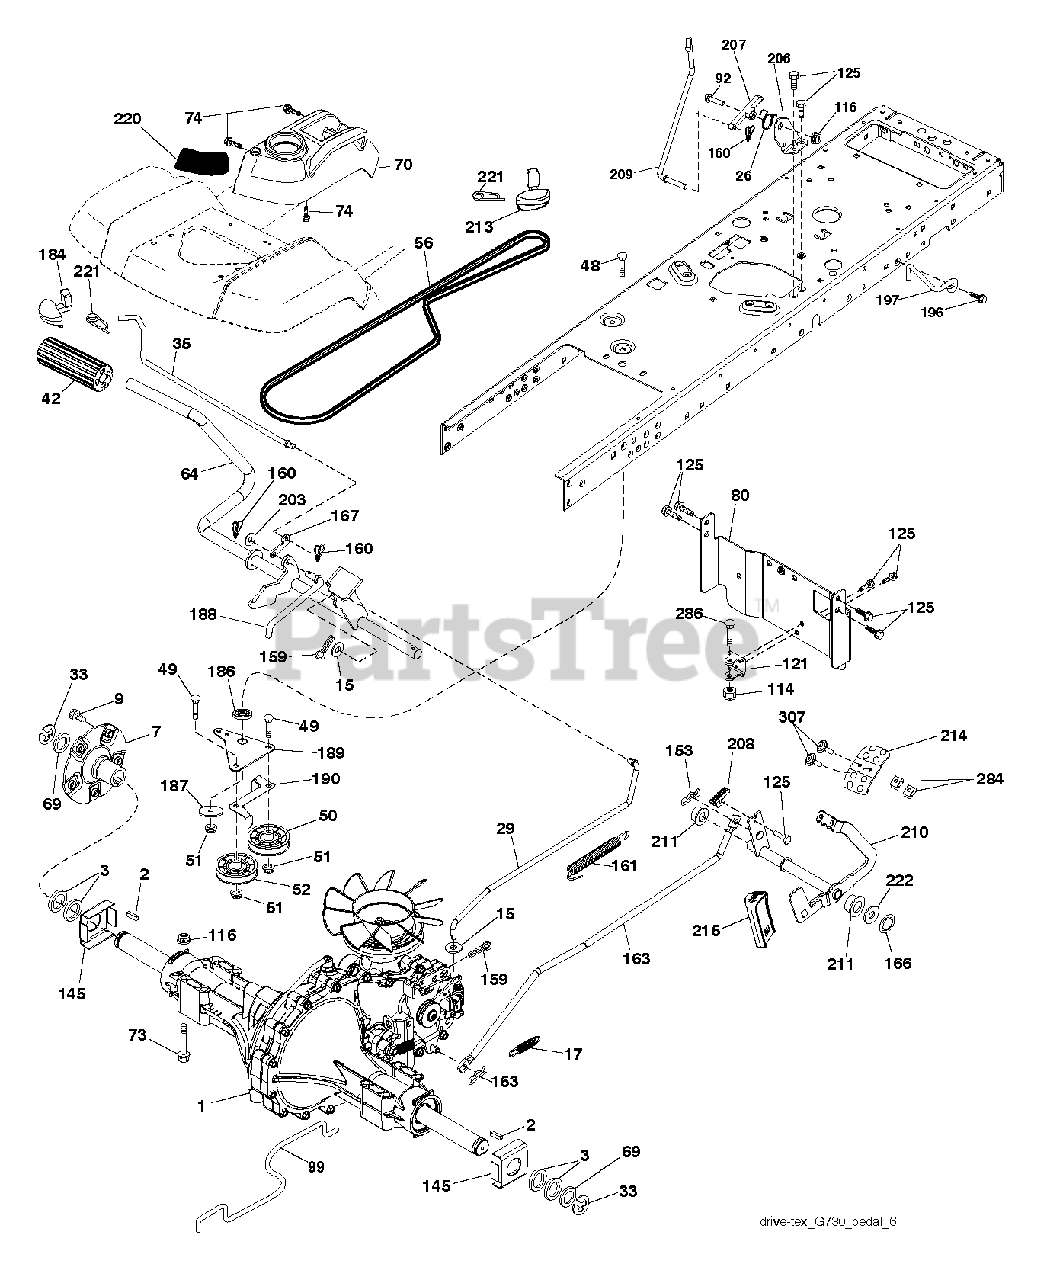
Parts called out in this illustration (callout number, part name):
2	KEY 1/4 X 2.5
7	HUB.ASM.WHEEL.REAR.23"TEX
15	WASHER
17	SPRING.BRAKE.HG3000/3500
26	SPRING.RETURN.CRUISE
33	E RING HYT
35	ROD.BRAKE.PARTK.HUSQ.TEX
42	PEDAL COVER T
48	BOLT.3/8-16X1.50
50	IDLER.FLAT.910.OFFSET
51	NUT LOCK FLG 3/8-16 UNC
52	IDLER.V-GROOVE.910.OFFSET
56	V-BELT.GROUND.DRIVE.
64	SHAFT.ASM.PEDAL.BRK.CNTR
70	CONSOLE.ASM.RH.GT.FC.HUSQ
73	BOLT HEX FLGHD 5/16-18X3 GR. 5
74	SCREW.HI-LO.CONSOLE
80	STRAP.TORQUE.YT.G700
92	BOLT
99	SPRING.BYPASS.YT.G700
114	NUT.71038.31-18.HEX.NYLOCK
116	NUT LOCK HEX FLANGE 5/16-18
121	BRACKET STRAP TORQUE
125	SCREW
145	WASHER.AXLE.FLANGE.HG-3000
153	RETAINER M
159	COTTER PIN
160	RETAINER CLIP
161	SPRING, RETURN LT
163	ROD PEDAL CONTROL
166	NUT.PUSH.625
167	LATCH.BRAKE.SPRING
184	RB HANDLE.PARKG.BRK.HUS/PRED
186	SPACER.RETAINER
187	WASHER 12/32X2X10GA
188	RP LINK.CLUTCH.GROUND.DRIVE
189	BELLCRANK.GROUND.DRIVE.TRAPPED
190	KEEPER BELLCRANK ROUND DRIVE
196	SCREW 3/8-16X1
197	BRKT.ANIT-ROTATION.CLUTCH
203	WASHER
206	BRKT.MOUNT.LATCH.CRUIS
207	LATCH.CONTROL.CRUISE
208	GEAR.SECTOR.CONTROL.CR
209	ROD.CONTROL.CRUISE.GT.
210	ROCKER.ASM.PEDAL.CONTR
211	BEARING.NYLON
213	KNOB.CONTROL.CRUSIE.HU
214	PEDAL.FORWARD.HUSQVARNA.DEALER
215	PEDAL.REVERSE.TEX.GT.4
220	REFLECTOR.RH.TEX GT
221	RETAINER.SPRING.CLIP.H
222	WASHER 21/32 X 1-1/4 X 10 GA.
284	NUT.U-CHNL.1/4-20.550DP.350PNL
286	BOLT.5/16-18X2.5
307	SCREW.MACHINE.CR.1/4-20
